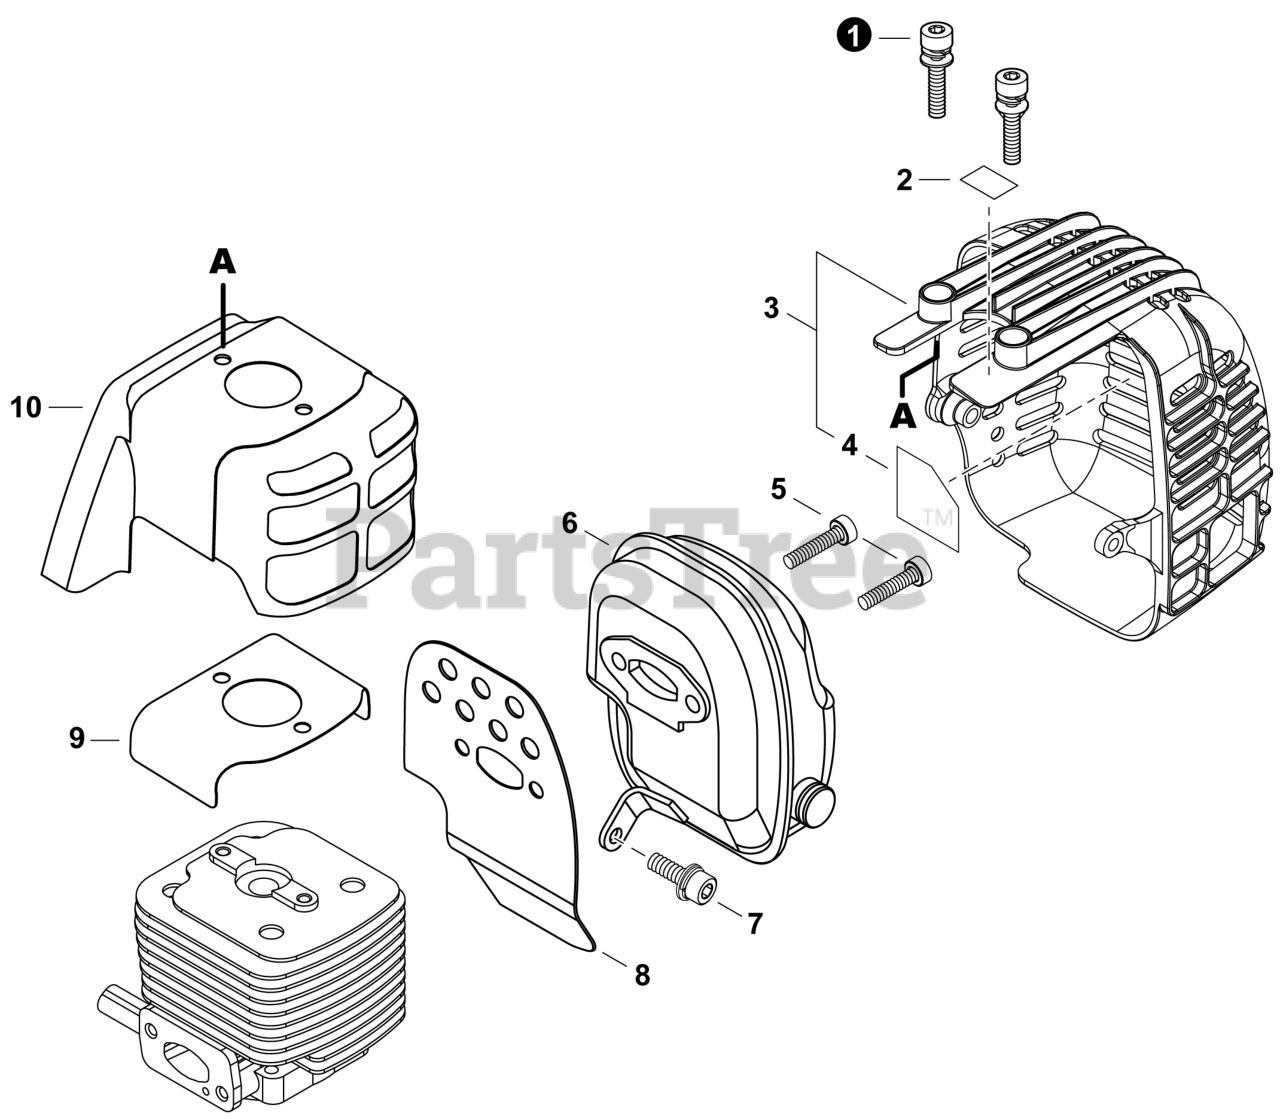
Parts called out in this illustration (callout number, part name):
1	BOLT M5x18
2	LABEL - CAUTION - HOT
3	COVER ASSY, MUFFLER
4	PLATE, INSULATOR
5	BOLT 6x25
6	MUFFLER
7	BOLT M5x12
8	HEAT SHIELD, EXHAUST
9	SHIELD, HEAT
10	COVER, ENGINE
